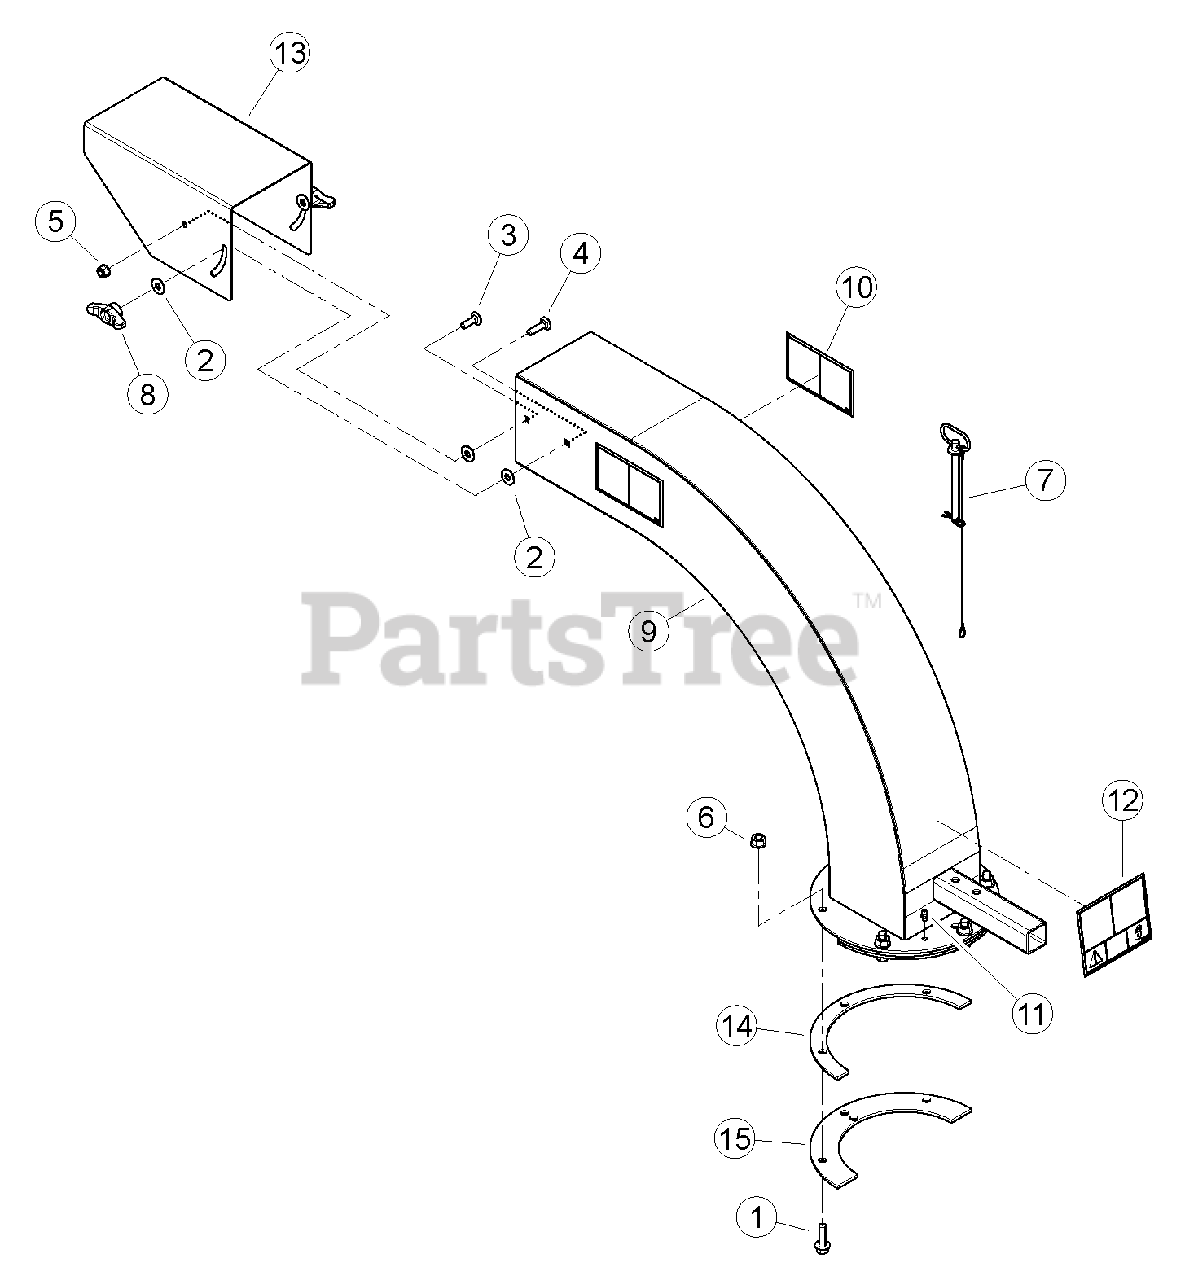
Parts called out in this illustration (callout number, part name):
1	BOLT, 3/8 X 1-1/4 FLANGE NC
2	WASHER, 5/16 FLAT ZP
3	BOLT, 5/16 X 1 GR5 CRG ZP
4	BOLT, 5/16 X 1-1/4 GR5 ZP CRG
5	NUT, 5/16-18 NYLOCK-FLANGE
6	NUT, 3/8-16 NYLOCK FLANGE
7	PIN, 3/8 X 4.25 DISCHARGE
8	KNOB, 5/16-18 UNC TEE W/LOCKING INSERT
9	ASSEMBLY, 6 INCH ORCHARD DISCHARGE CHUTE, SERVICE PART
10	DECAL, DISCHARGE ISO
11	FITTING, 1/4 SELF-TAP GREASE
12	DECAL, DISCHARGE DEBRIS & LOCK
13	CAP, 6 INCH ORCHARD DISCHARGE
14	SPACER, DISCHARGE PIVOT
15	RING, DISCHARGE CLAMP
